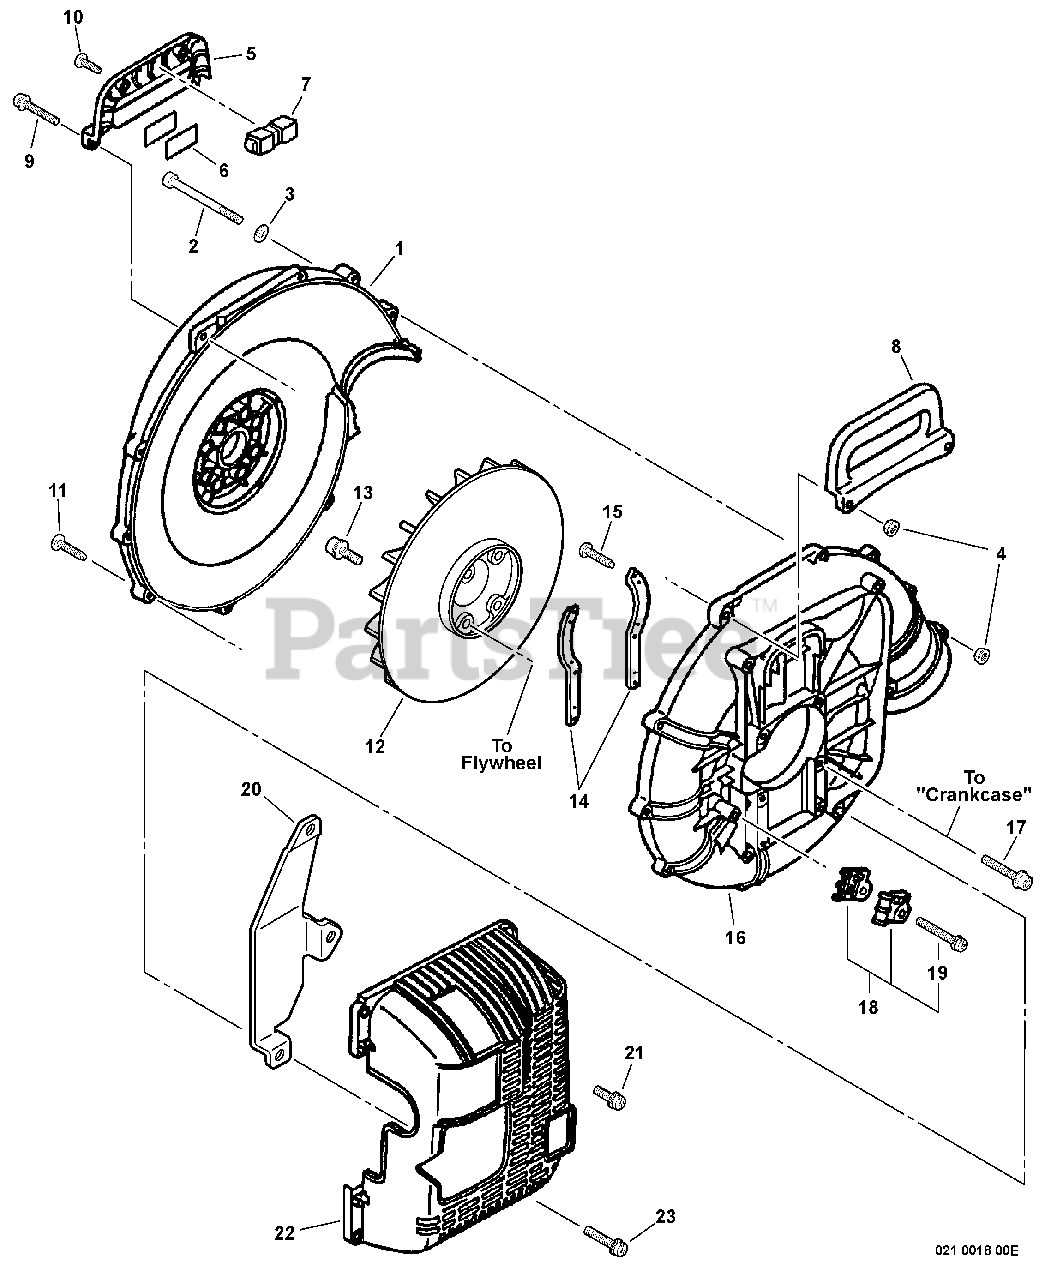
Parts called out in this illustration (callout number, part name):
1	COVER, FAN - INNER
2	BOLT 5×60
3	WASHER 5.3×10×1
4	NUT, FLANGE M5
5	HANDLE
9	SCREW 5×45
10	SCREW 5×16
11	SCREW 5×30
13	BOLT 5×20
14	BRACKET, ENGINE
15	SCREW TAPPING 3×12
16	COVER, FAN - OUTER
17	SCREW 5×32
18	CABLE HOLDER KIT
19	SCREW 5×25
20	INSULATOR
21	SCREW 5×10
22	COVER, ENGINE
23	SCREW 5×18
